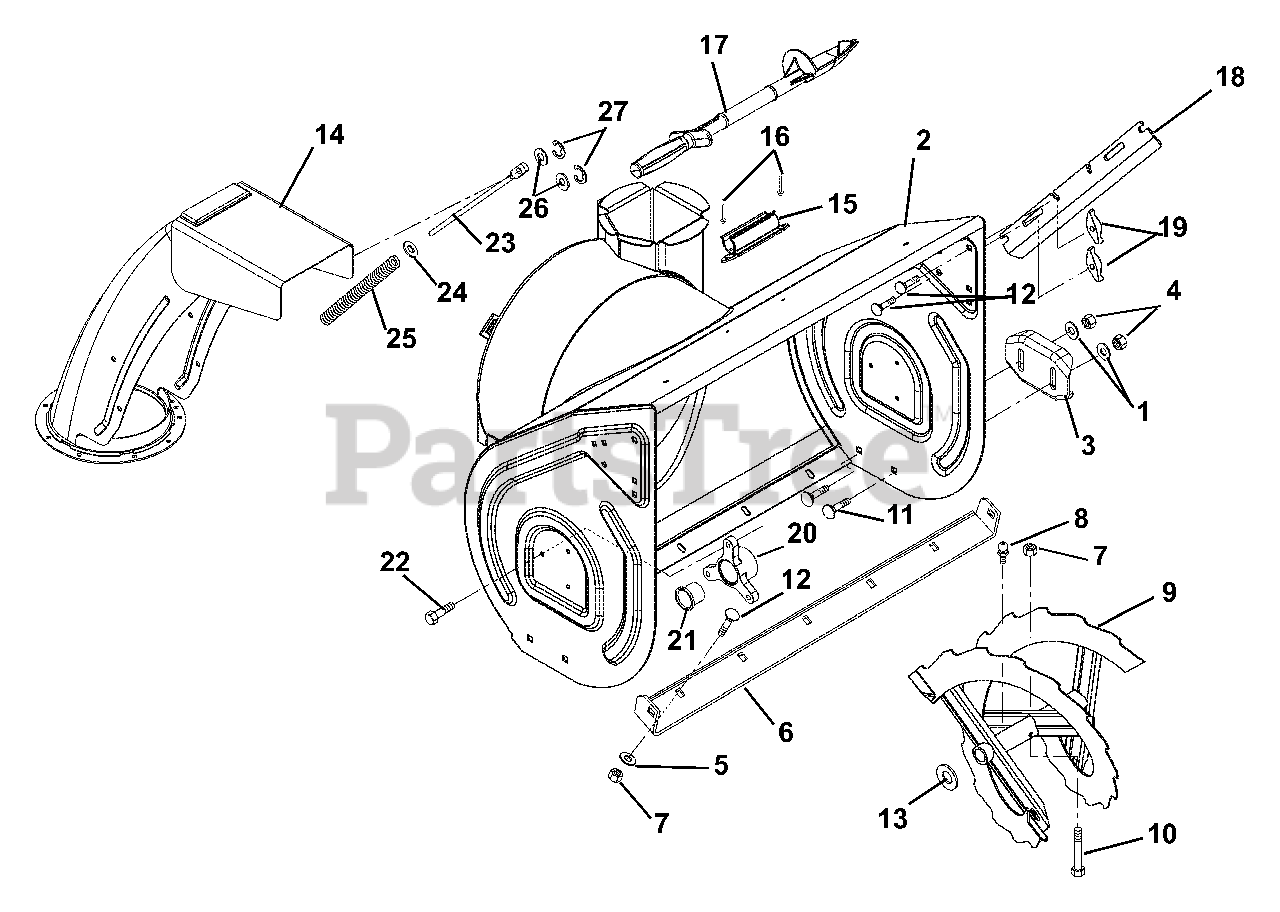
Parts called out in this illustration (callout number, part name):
1	@WSHR-FL-STL.438X1.00X.083 YWZ
2	HOUSING, 26" W/DECAL
3	SKID SHOE, REVERSIBLE - ORANGE
4	@NUT-LK-CTR .38-16 YWZC
5	@WSHR-FL-STL.38X.875X.083 YWZC
6	BLADE, SCRAPER-26"
7	@NUT-LK-CTR .31-18 YWZC
8	FTG-LUBE .25-28X.256 YWZC
9	RAKE, LH-26"(1 ID X 15.75 OD)
10	SHEAR BOLT SERVICE ASSEMBLY
11	@BLT-RDHDSHSQNK.38-16X1.0 G5YZ
12	@BLT-RHDSSQNK .31-18X.75 G5YZ
13	WSHR-FL-STL 1.010X1.505X.062YZ
14	CHUTE, DISCHARGE-W/REMOTE
15	MOUNT, SNOW CLEAN OUT
16	RVT-POP .187X.45 DOME SS FBF64
17	DEVICE, SNOW CLEAN OUT
18	CUTTER, DRIFT
19	KNOB - WING .312-18 UNC
20	BUSHING, RAKE SHAFT 1"
21	BSHG-FLG, SPLIT NYLINER 1.0"ID
22	@SCR-TAP .25-20X.50 HWH TR YWZ
23	ROD, CHUTE
24	@WSHR-FL-STL.344X.688X.065YWZC
25	SPRING, COMP. .08 X .40 X 7.15
26	@WSHR-FL-STL.281X.62X.065 YWZC
27	RG-RTNG-EXT .218X.035 TYPE E
